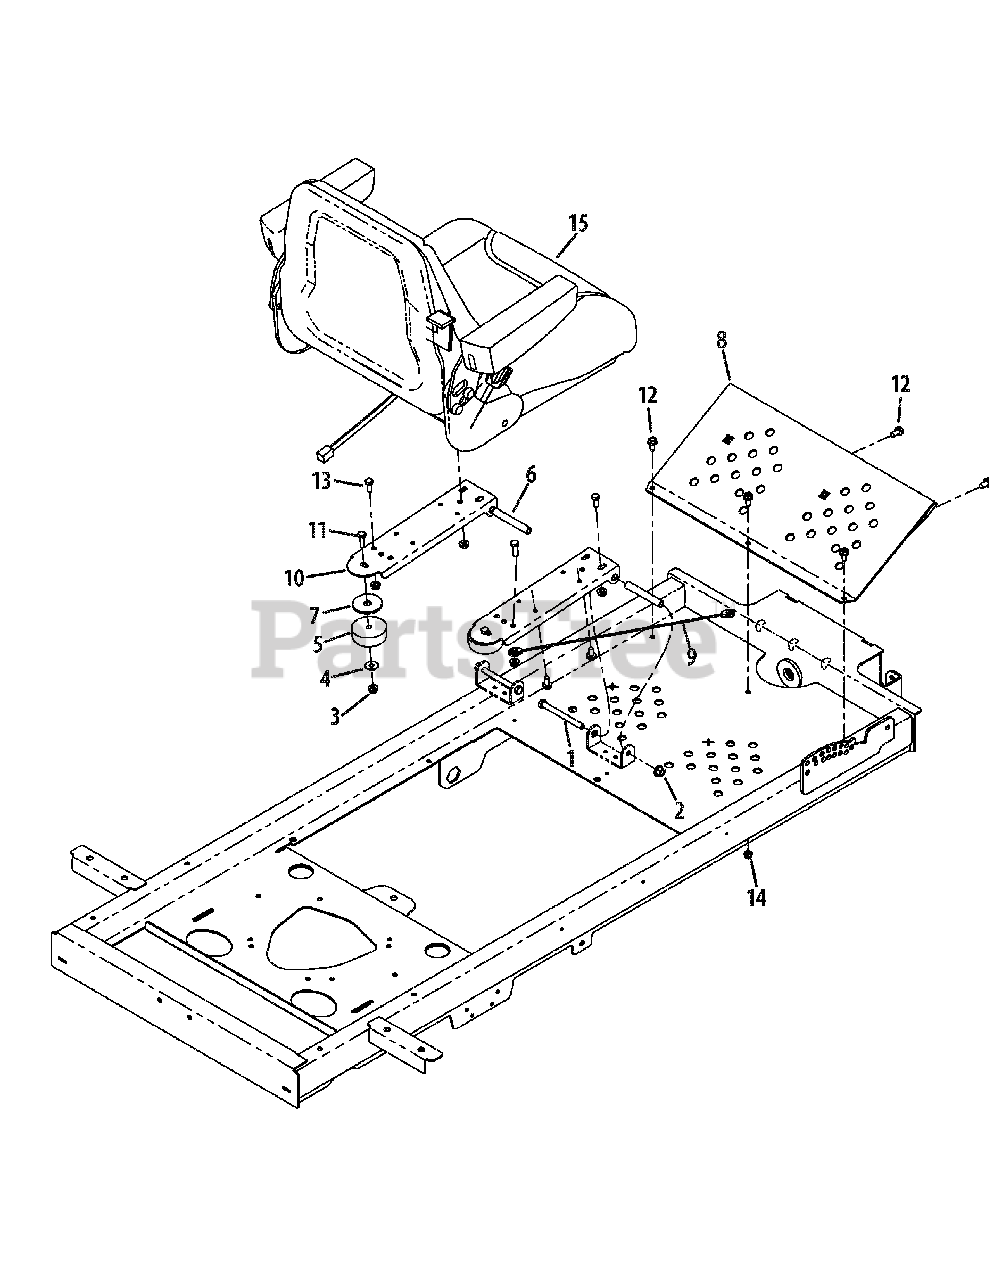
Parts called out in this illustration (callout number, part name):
1	Hex Screw, 3/8-16 x 4.00
2	Flange Counterlock Nut, 3/8-16
3	Flange Counterlock Nut, 5/16-18
4	Bell Washer, .325 x .930 x .045
5	Grommet, 2.5 x 1.0
6	Spacer, .370 x .500 x 3.45
7	Washer, .53 x 2.13 x .134
8	Foot Rest Bracket
9	Cable Support, 16.16
10	Seat Mount Bracket
11	Hex Screw, 5/16-18 x 1.00
12	Hex Washer Screw, 5/16-18 x .750
13	Hex Screw, 5/16-18 x .75
14	Hex Lock Nut, 5/16-18
15	Suspension Seat
